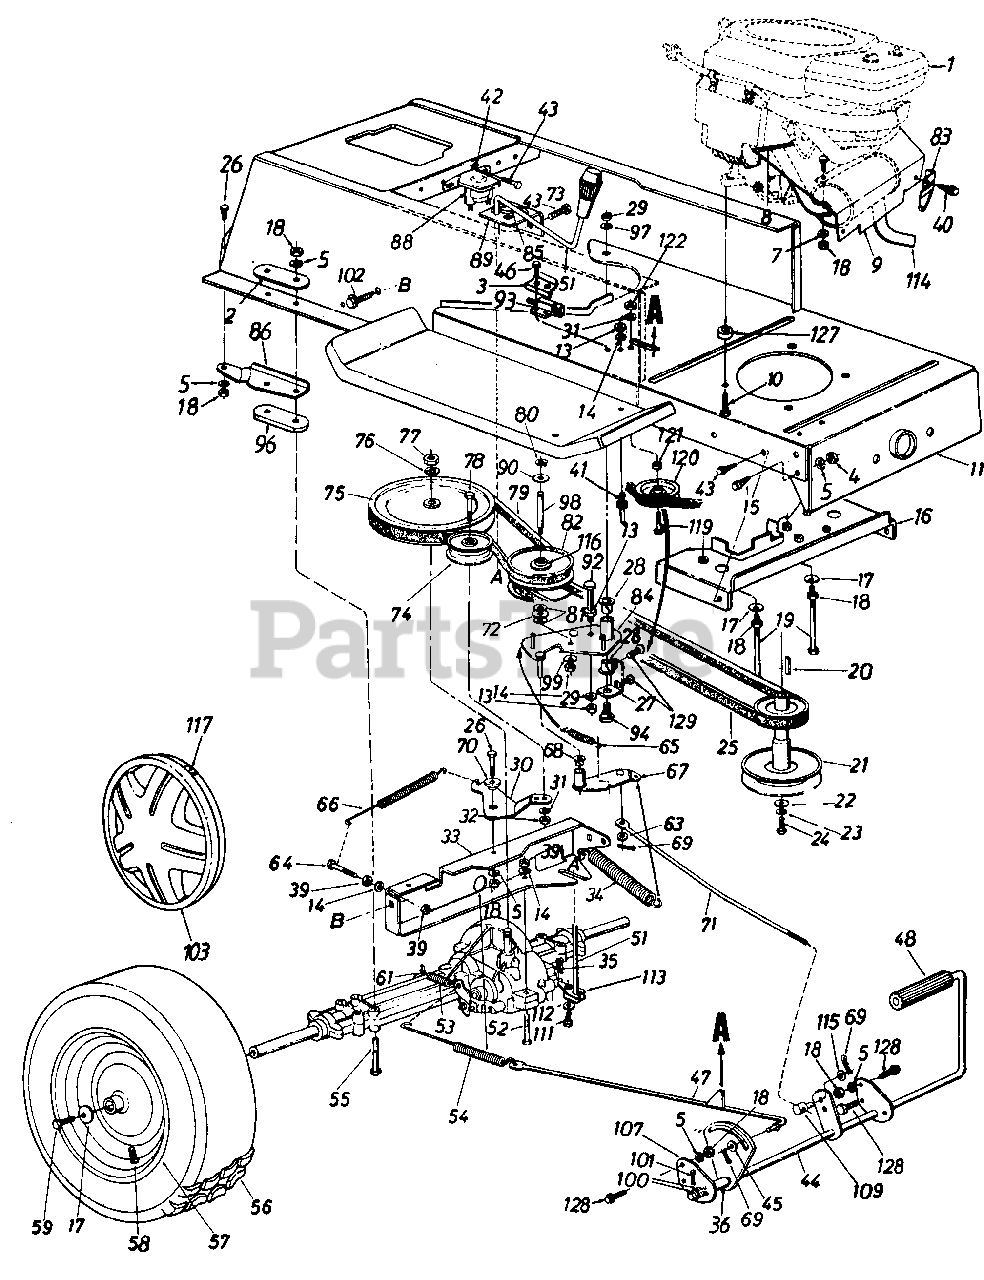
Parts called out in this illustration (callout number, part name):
1	Engine
3	Switch Plate
4	Hex Nut 5/16-24 Thd.
5	L-Wash. 5/16" I.D.
7	Spec. L-Wash. .38" I.D. x .88"
8	Trim Strip
9	Front Heat Shield
10	Hex L-Wash. Tap Scr. 3/8-16 x 1.5" Lg.
11	Lower Frame Ass'y.
13	Hex Nut 1/4-20 Thd.*
14	L-Wash. 1/4" I.D.
15	Hex TT-Tap Scr. 5/16-18 x .62"
16	Belt Guard Brkt. Ass'y.
17	Bell-Wash. .345" I.D. x .88"
18	Hex Nut 5/16-18 Thd.
19	Hex Bolt 5/16-18 x 4.0"
20	Sq. Key 1/4" x 1/4" x 2.00"
21	Engine Pulley
22	Fl-Wash. 7/16" I.D. x 1.25"
23	L-Wash. 7/16" I.D.
24	Hex Bolt 7/16-20 x 1.50" Lg.
25	Variable-Speed Belt
26	Hex Bolt 5/16-18 x .75" Lg.
27	Bearing Shaft Bracket Ass'y.
28	Flanged Nyliner Brg. 5/8" I.D. x .88" Lg.
29	Hex Nut 3/8-24 Thd.
31	L-Wash. 3/8" I.D.
32	Hex Nut 3/8-24 Thd.
33	Transaxle Support Brkt.
34	Ext. Spring .94" O.D. x 7.58"
35	Inter. Cotter Pin
36	Spacer.63" I.D.
39	Hex Nut 1/4-28 Thd.
40	Hex AB-Tap Scr. 1/4" x .62" Lg.
41	Belt Guard Pin
42	Ext. L-Wash. 1/4" I.D.
43	Hex Wash. Hd. S-Tap Scr. 1/4-20 x .50" Lg.
44	Clutch/Brake Pedal Ass'y.
45	Fl-Wash.
46	Truss Mach. Scr. B-Tap Scr. #10 x .5" Lg.
47	Brake Rod Ass'y.
48	Foot Pad
51	Shift Lever Ass'y.
52	Hex Bolt 1/4-28 x 1.75" Lg.
53	Ext. Spring .38" O.D. x 2.5"
54	Ext. Spring .59" O.D. x 7.08"
55	Hex Bolt 5/16-18 x 3.5" Lg.
57	Wheel Rim Only
58	Air Valve
59	Hex Bolt 5/16-24 x .75" Lg.*
61	Brake Return Spring Anchor
63	Fl-Wash. .34" I.D. x .68" O.D.
64	Hex Bolt 1/4-28 x 1.25" Lg.
65	Ext. Spring
66	Ext. Spring .62" O.D. x 6.12"
68	Flanged Bearing
69	Cotter Pin 3/32" Dia.
70	Shoulder Spacer .27" Lg.
71	Speed Control Link
72	Truss Bearing .56 Dia. x 1.25"
73	Shift Knob
74	Fl-Idler Pulley 3.25" x .75"
75	1/2" "V"-Pulley
76	L-Wash. 1/2" I.D.
77	Hex Jam Nut 1/2-20 Thd.
78	Hex Bolt 3/8-24 x 1.75" Lg.
79	Variable Speed Belt
80	Snap Ring .56" Dia.
81	Fl-Wash.
82	Variable Speed Pulley Ass'y. 5" O.D.
90	Teflon Washer .565" I.D.
92	Hex Bolt 1/4-20 x 3.25" Lg.
93	Safety Switch
94	Shld. Bolt 3/8-24 x 3.12" Lg.
96	Transaxle Spacer
97	Bell-Wash. .38" I.D. x .88"
98	Shaft .56" Dia. x 3.875" Lg.
99	Bell-Wash. .39" I.D. x 1.12"
100	Fl-Wash. .64" I.D. x .94"
101	Cotter Pin 1/8" Dia. x 1.25"
102	Hex Wash. Hd. Scr. 5/16-18 x.62" Lg.
103	Hub Cap
109	Ferrule
111	Hex Bolt 1/4-28 x .50" Lg.
112	Bell-Wash. .265" I.D. x .75"
113	Shift Lever Link Ass'y.
114	Muffler
115	Fl-Wash. .385" I.D. x .62"
116	Needle Brgs.
117	Spring Clip
119	Hex Bolt 3/8-16 x 1.25" Lg.
120	Fl-Idler w/Flanges 2.75" O.D.
121	Fl-Wash. .39" I.D. x 1.12" O.D.
122	Hex Nut 3/8-16 Thd.
127	Spacer 5/16" I.D.
128	Hex Wash. TT-Tap Scr. 5/16-18 x.75" Lg.
129	Hex Wash. AB-Tap Scr. 5/16-18 x.75" Lg.
